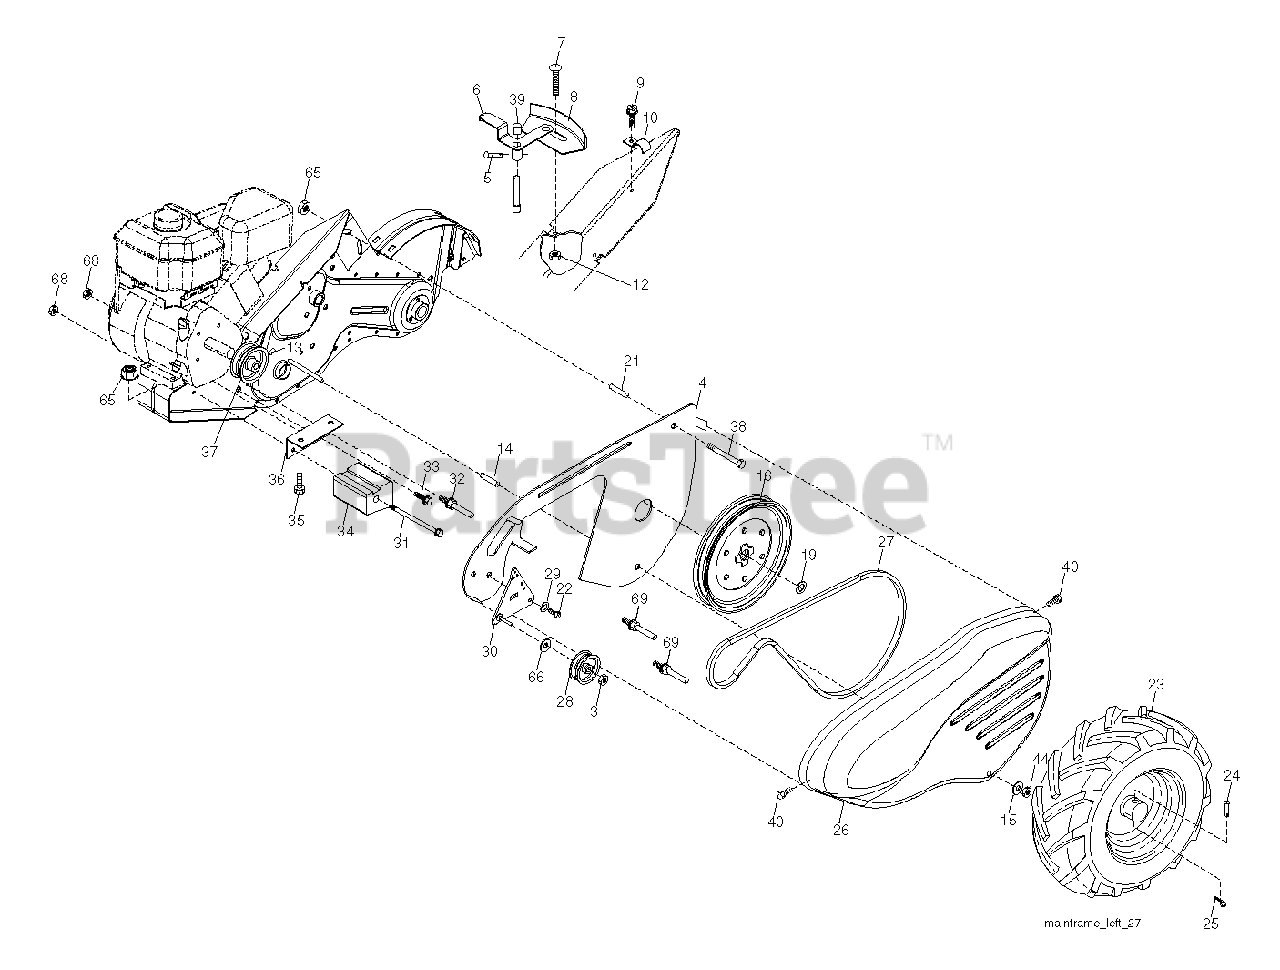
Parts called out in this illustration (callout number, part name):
3	LOCKNUT
4	SHIELD.INNER.BELT.GUARD.RT
5	PIN.SPIROL.FLARED
6	LEVER.ASM.SHIFT.RED
8	RP.PANEL.SHIFT
10	CONDUIT CLIP T
12	NUT
13	SET SCREW
14	SPACER-SPLIT.327 X .42
15	WASHER
16	SHEAVE, TRANSMISSION
19	RETAINING RING LT
21	SPACER CRT
23	TIRE.CHV.13X5-6
24	RIVET,DRILLED
26	GUARD.BELT.TILLER.YELLOW
27	V-BELT
28	PULLEY-IDLER TI
29	KLIP RING
30	BRACKET.ASM.IDLER.BLACK
31	BOLT.FIN.HEX.3/8-16UNC
32	SHIFT ARM CRT
33	BOLT
34	COUNTERWEIGHT.LH.CRT
35	BOLT, HEX 5/16-18X1-3/4
36	BRACKET LH CRT
37	ENGINE PULLEY
39	CAP.PLUNGER.BLACK
40	SCREW.HEX.WSH.SLT.#10-24X.50
44	NUT.71038.31-18.HEX.NYLOCK
65	LOCKNUT-FLANGE 5/16-18
66	WASHER
69	KEEPER.BELT.ENGINE
